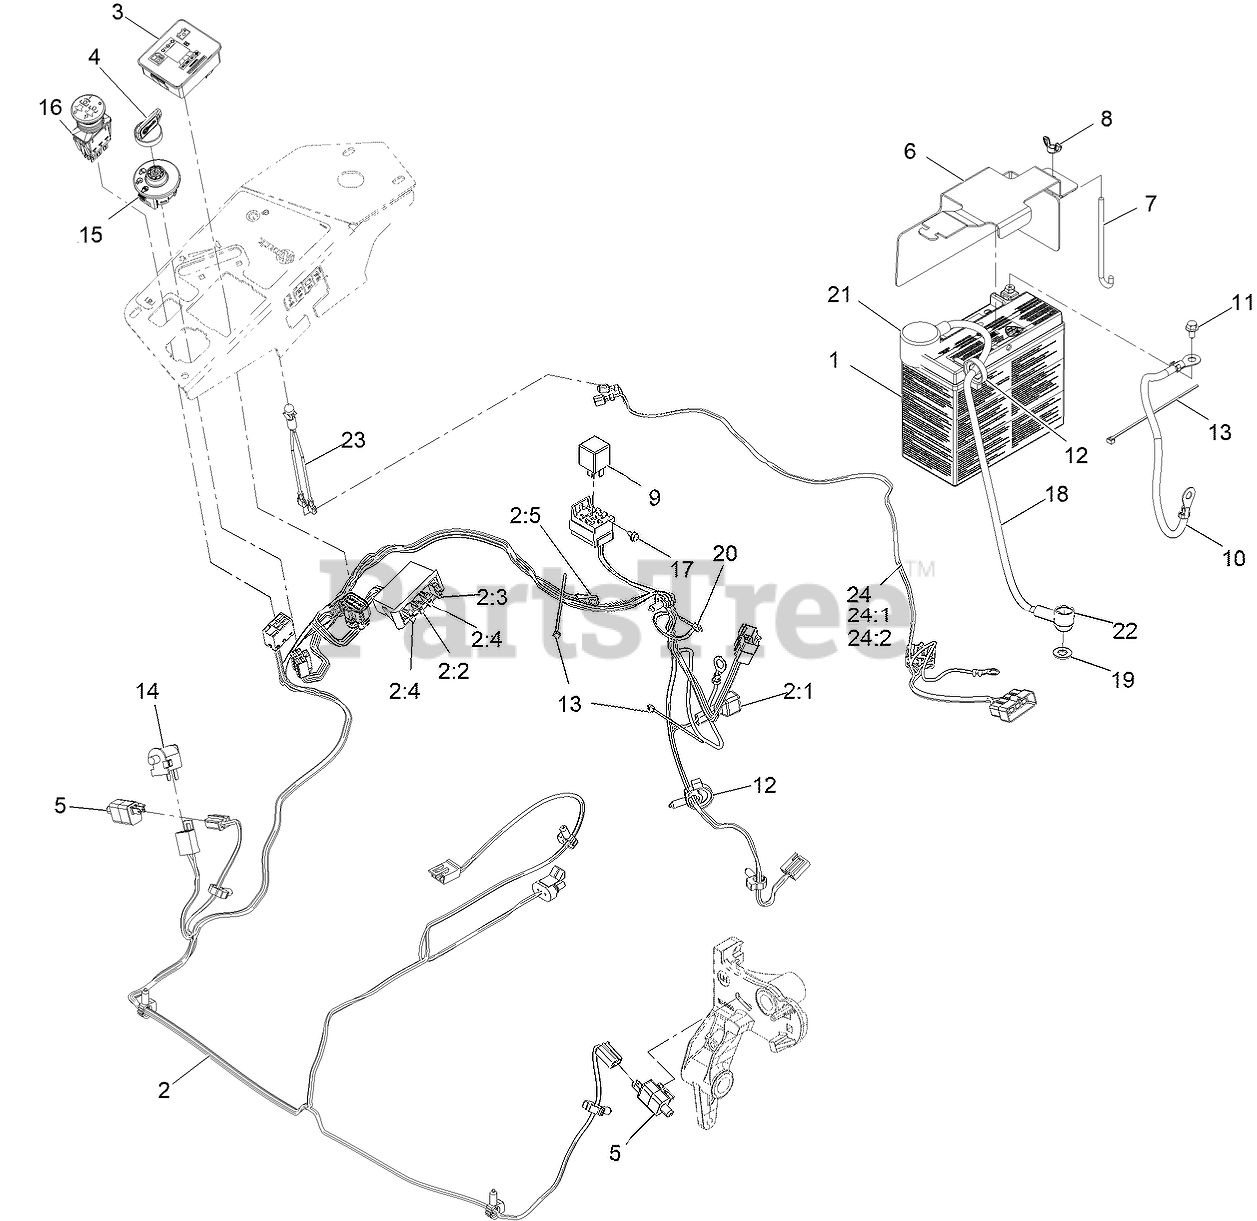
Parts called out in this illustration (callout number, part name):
1	BATTERY-AGM
2	HARNESS-WIRE, MAIN
2:2	FUSE-BLADE, 10 AMP
2:3	FUSE-BLADE, 15 AMP
2:4	FUSE-BLADE, 25 AMP
2:5	CAP-PLUG
3	FUEL/HOUR METER ASM
4	KEYS-IGNITION (SPARE PAIR
4	KEY-IGNITION
6	BRACKET-HOLDDOWN, BATTERY
7	BOLT-HOLDDOWN
8	WINGNUT
10	Cable-Battery, Black
11	SCREW-HHF
12	CLAMP-HOSE
13	TIE-CABLE
14	SWITCH-BAIL
15	SWITCH-IGNITION
16	SWITCH, PTO 10A
17	SCREW-HWH
18	CABLE-BATTERY, POSITIVE
19	WASHER-FLAT
20	TIE-CABLE
21	INSULATOR-BATTERY
22	INSULATOR-SOLENOID
23	INDICATOR-LED, RED
24	HARNESS-INDICATOR LIGHT
24:1	Tubing, Conv, 1/4", Hi Temp, Uv Inhibit
24:2	Tubing, Conv, 7/16", Hi Temp, Uv Inhibit
